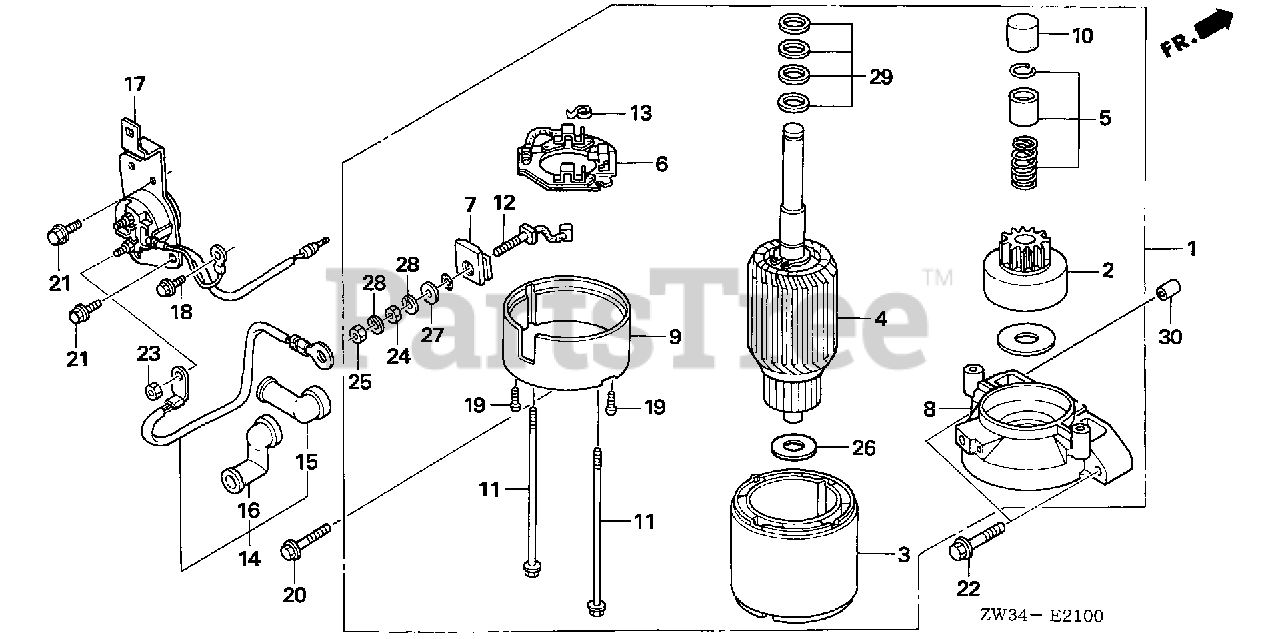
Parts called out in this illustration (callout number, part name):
1	STARTER MOTOR ASSY.
2	CLUTCH, OVERRUNNING
5	STOPPER SET, PINION
6	HOLDER, BRUSH
8	BRACKET, FR.
9	BRACKET, RR.
10	CAP, STOPPER
11	BOLT, THROUGH
13	SPRING, BRUSH
18	BOLT, FLANGE (6X12) (CT200)
19	SCREW (4MM)
20	BOLT, FLANGE (6X28)
21	BOLT, FLANGE (6X12)
22	BOLT, FLANGE (8X45)
26	WASHER, RR.
27	WASHER (1)
28	WASHER (2)
29	WASHER SET, THRUST
30	PIN, DOWEL (10X16)
